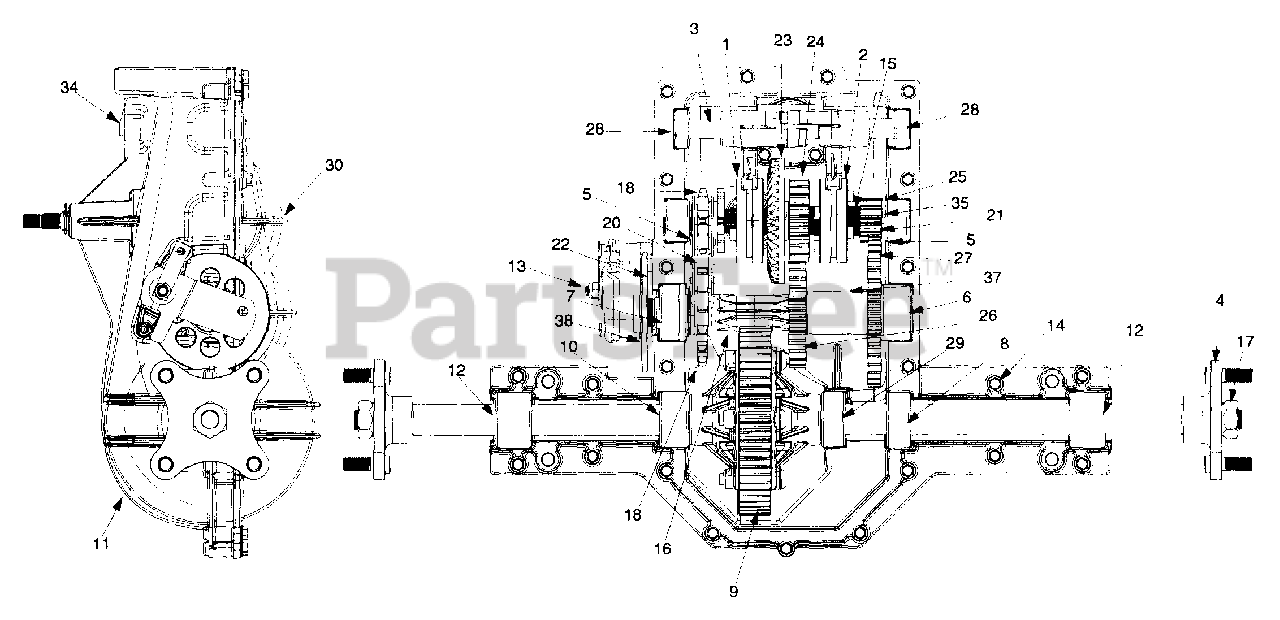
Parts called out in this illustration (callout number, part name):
1	Collar Ass'y.- Reverse
2	Collar Ass'y.- Hi-Lo
3	Shift Fork Ass'y.
4	Wheel Hub Ass'y.
5	Drive Shaft Blk. Ass'y.
6	Output Brg. Blk. Ass'y.
7	Output Brg. Blk. Ass'y. Seal
8	Inboard Axle Blk. Ass'y,
9	Differential Axle Ass'y.
10	Inboard Axle Blk. Ass'y.
11	Upper Housing Ass'y.
12	Axle Brg. Blk. Ass'y.
13	Bracket Ass'y. - R.H.
14	Hex Wash. TT-Tap Scr. 1/4-20 x 1" Lg.
15	Drive Shaft
16	Output Shaft - R.H.
17	Hex Nut 3/4-16
18	Sprocket 9T
20	Chain Endless
21	Ext. Snap Ring
22	Brake Pad
23	Bevel Gear 41T
24	Spur Gear 20T
25	Spur Gear 107
26	Spur Gear 27T
27	Spur Gear 37T
28	Shifter Brg. Blk.
29	Inner Axle Blk. Brg.
30	Lower Housing
34	Shipping Plug
35	Fl-Wash. 5/8" I.D. x 1" O.D.
37	Spacer 1.13" I.D. x 1.38" O.D.
38	Disc Brake
